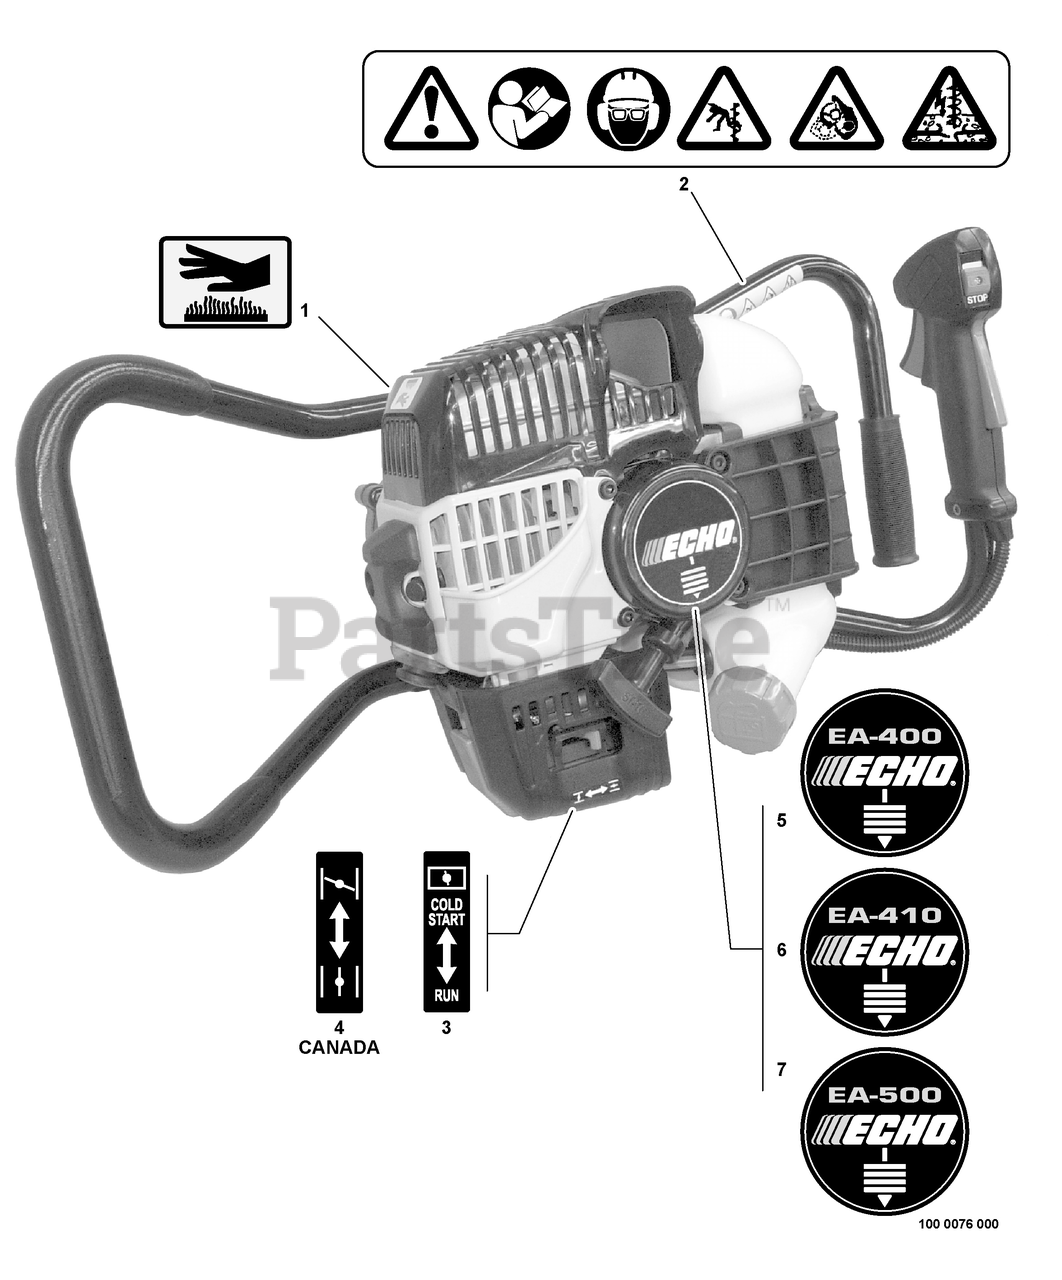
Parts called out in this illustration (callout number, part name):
1	LABEL - HOT SURFACE
2	LABEL - CAUTION
3	LABEL - CHOKE
4	LABEL - CHOKE
5	LABEL - MODEL EA-400
6	LABEL - MODEL EA-410
7	LABEL - MODEL EA-500
